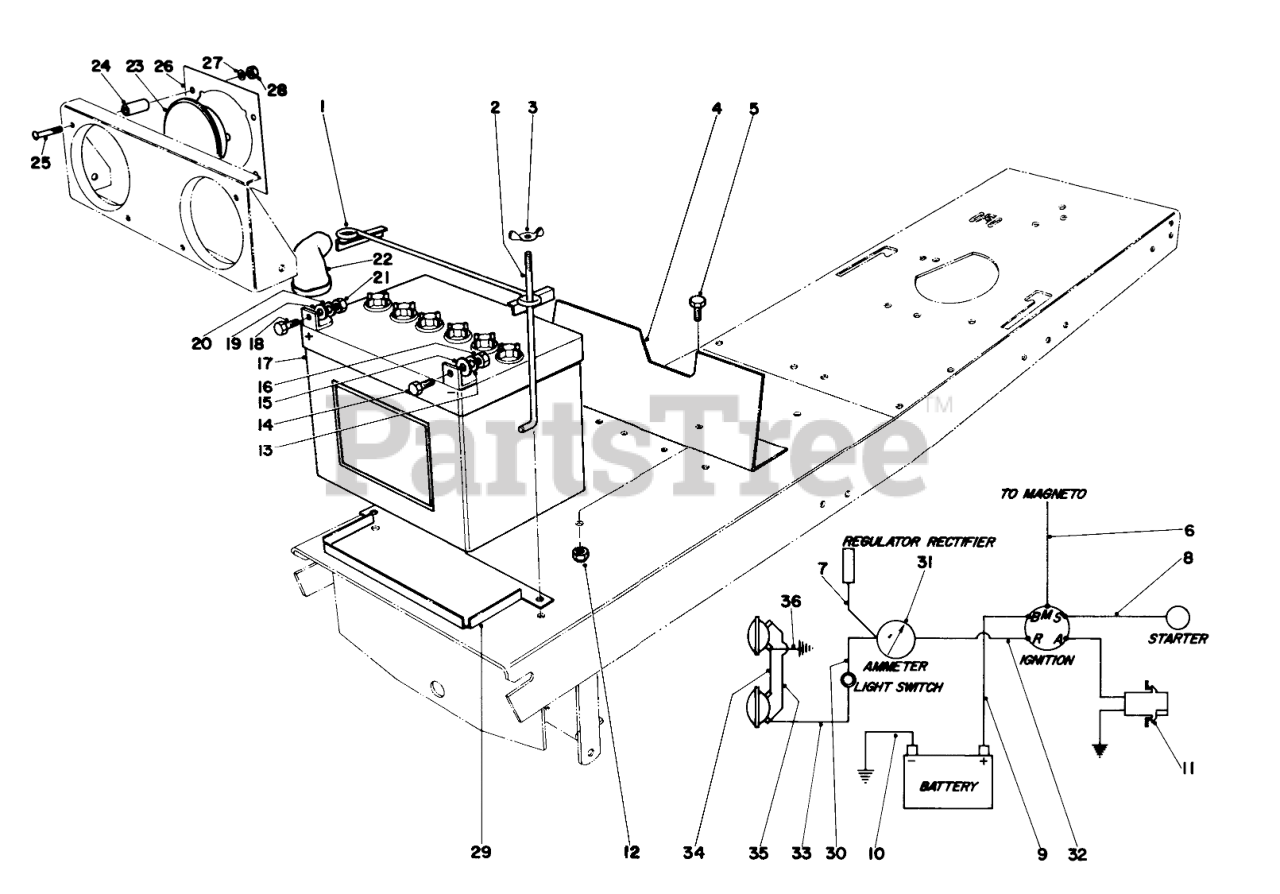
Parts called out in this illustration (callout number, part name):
1	Battery Clamp
2	BATTERY BOLT
3	WING NUT
4	Heat Shield
5	SCREW-HH
6	Wire Switch to Battery
8	Wire Assy. Switch to Starter
9	Wire Assy. Switch to Battery
10	Wire Assembly
11	Wire Assembly
12	Nut
13	WASHER-LOCK
14	SCREW-HH
15	WASHER-FLAT
16	NUT-HEX
17	Battery
18	SCREW-HH
19	Washer
20	WASHER-LOCK
21	NUT-HEX
22	Battery Boot
23	HEAD LAMP
24	Spacer
26	Headlight Holder
27	WASHER-LOCK/SP
28	NUT-HEX
29	Retainer Battery
31	Ammeter
32	Wire Assy. Ammeter to Switch
33	Wire Assy.
34	Wire 960
35	Wire 960
36	Wire Assy.-Red
